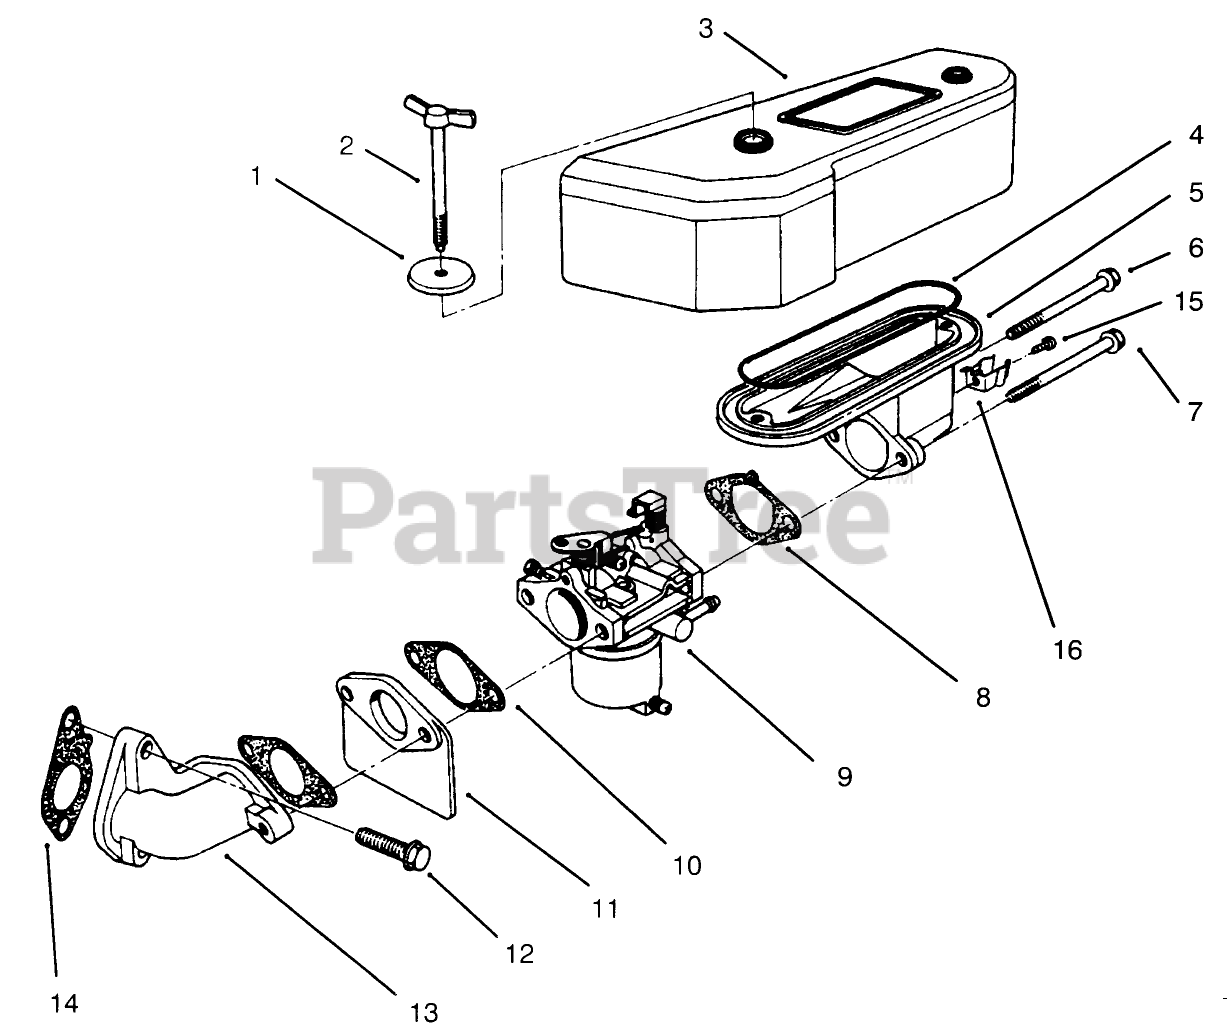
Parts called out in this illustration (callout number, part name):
1	Washer
2	Bolt
3	Air Filter Assy (includes items 32, 33, 34 35)
4	Gasket
5	Pipe-Intake
6	Bolt
7	Bolt
8	Gasket
9	Carburetor ASM
10	Gasket
11	Insulator
12	Bolt-Flanged (8X25)
13	Pipe-Intake
14	Gasket
15	Screw
16	Clamp
